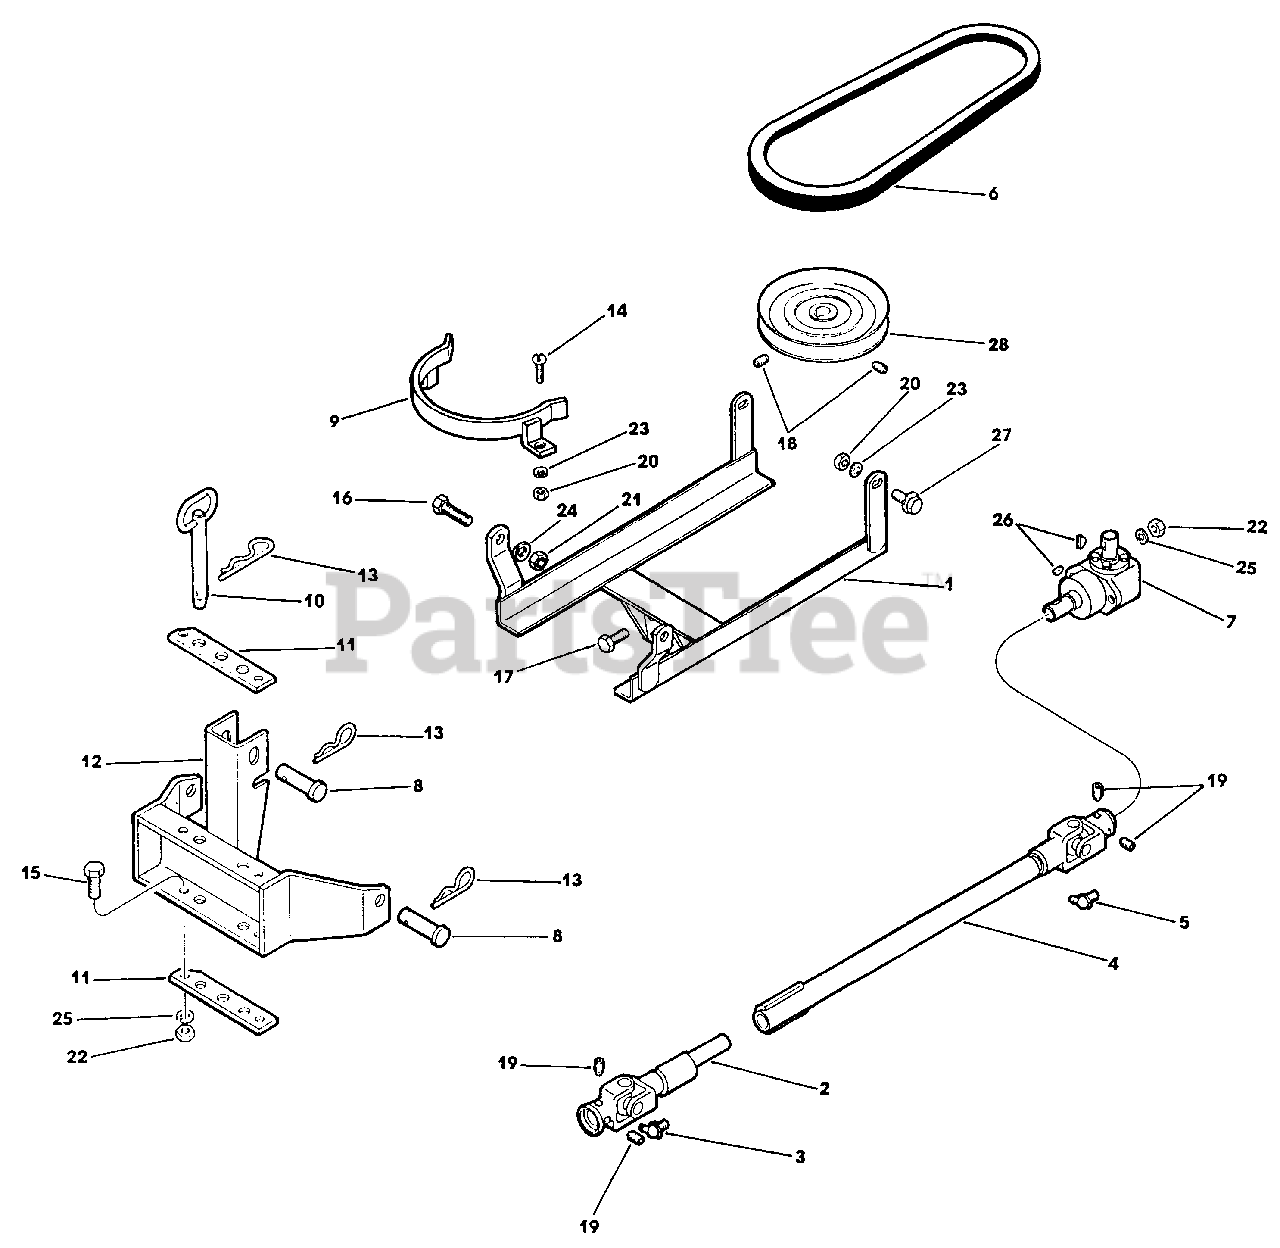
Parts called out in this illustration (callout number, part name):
1	Support Assembly-P.T.O
2	Assembly-Universal Joint
3	Grease Fitting
4	Assembly-Drive Tube
5	Grease Fitting
7	Gear Box
8	Clevis Pin
9	Guard Assembly-Belt
10	Hitch Pin
11	Wear Plate
12	Assembly-Hitch Plate
13	Spring Clip
14	Machine Screw Round Hd
15	Cap Screw, Hex Hd
16	Cap Screw, Hex Hd.
17	Cap Screw, Hex Hd
18	Set Screw, Hex Socket Hd. Cup Pt
19	Set Screw, Hex Socket Hd. Cup Pt
20	Nut, Hex
21	Nut, Hex
22	Nut, Hex
23	Washer, Spring Lock
24	Washer, Spring Lock
25	Washer, Spring Lock
26	Key, Woodruff
27	Screw, Thread Forming
28	Pulley-7"
